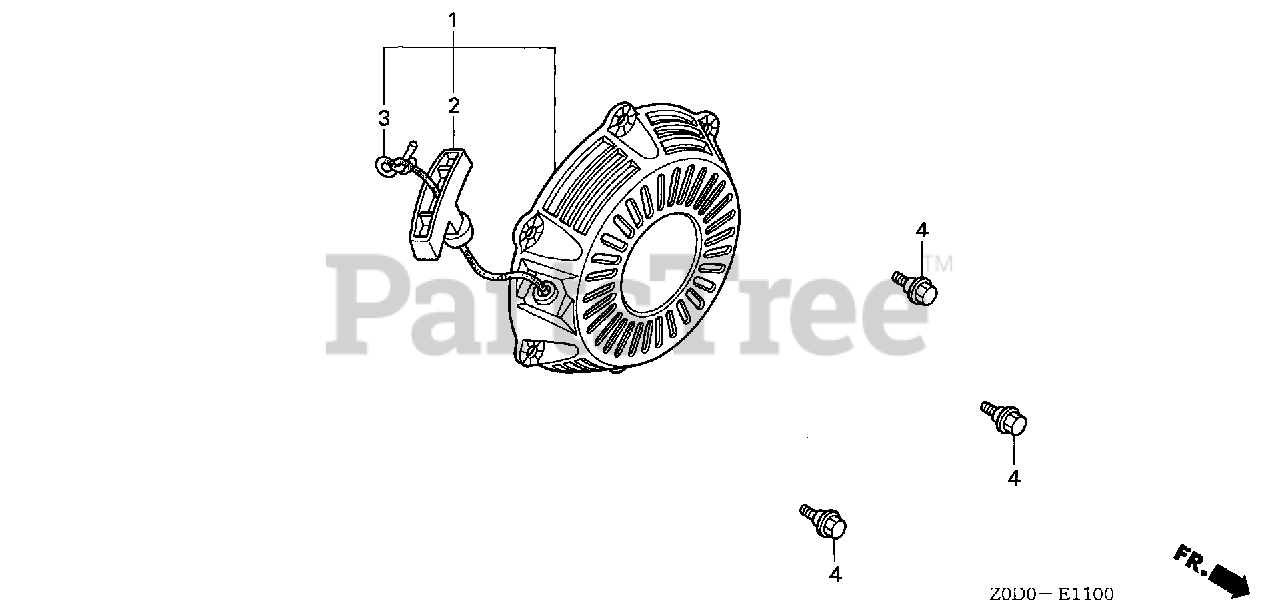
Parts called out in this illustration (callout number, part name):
1	STARTER ASSY., RECOIL *R8* (BRIGHT RED)
1	STARTER ASSY., RECOIL *NH1* (BLACK)
2	GRIP, STARTER
3	ROPE, STARTER
4	BOLT, FLANGE (6MM)
